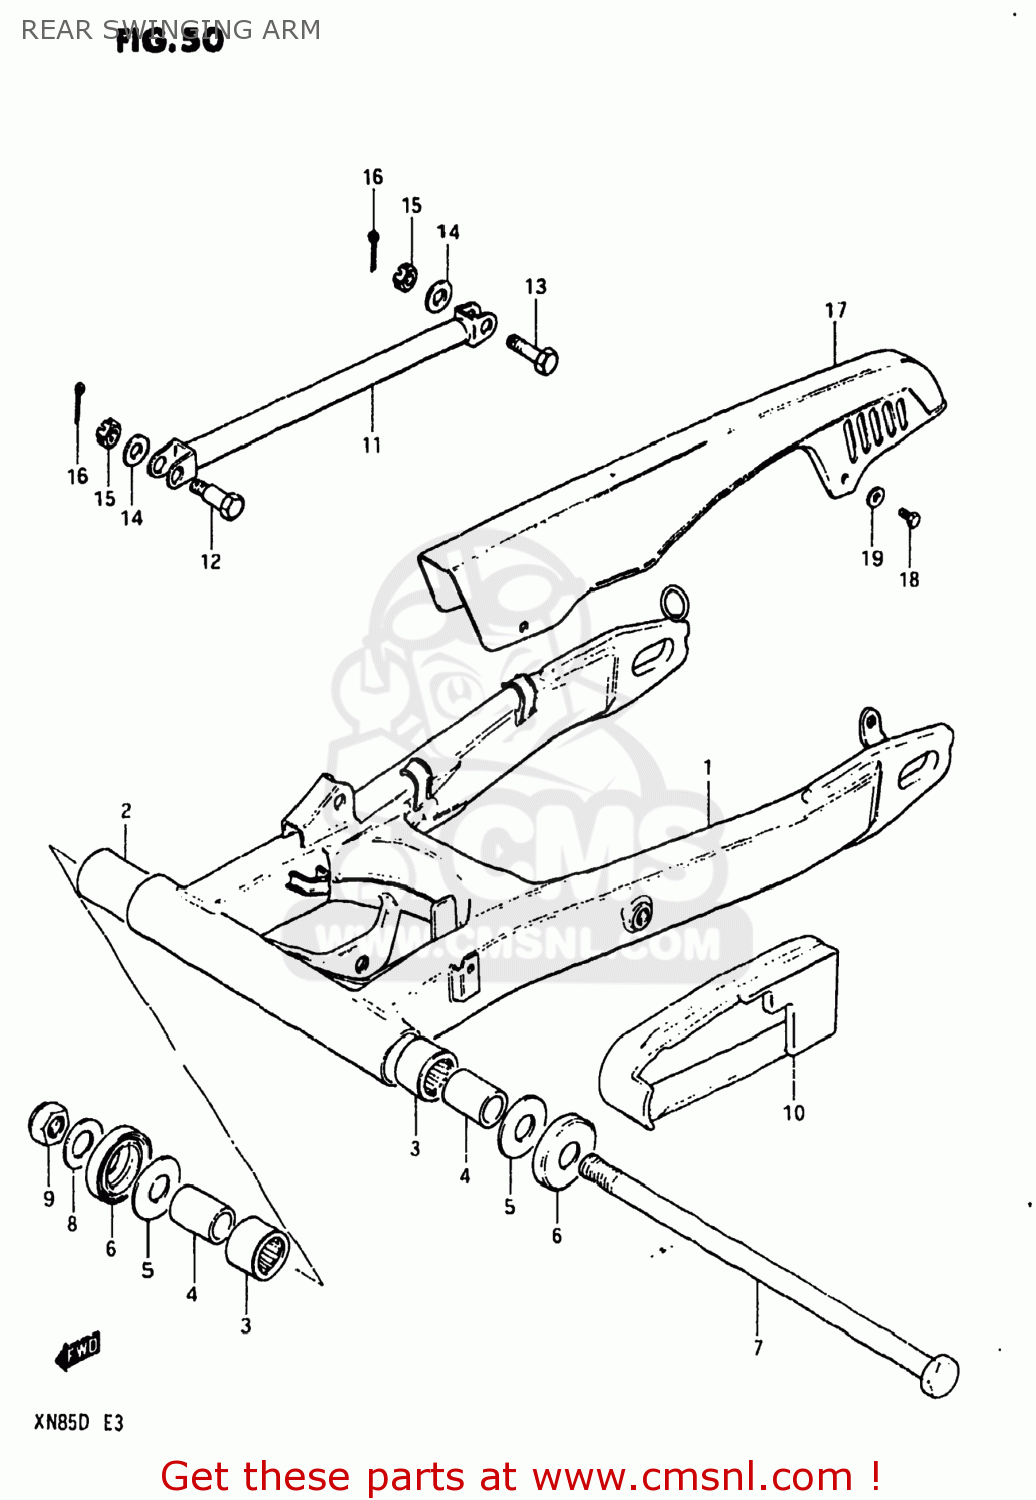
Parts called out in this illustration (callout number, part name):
1	ARM,REAR SWING
2	SPACER,SWING ARM,CENTER
3	BEARING(25X33X30)
4	SPACER,RR SWGARM PIVOT
5	WASHER
6	COVER,RR SWGARM DUST SEAL
7	SHAFT,REAR SWING ARM
8	WASHER
9	NUT
10	BUFFER,CHAIN TOUCH DEFLECTOR
11	LINK,REAR TORQUE
12	BOLT
13	BOLT(10X39)
14	WASHER
15	NUT
16	PIN 20X20
17	CASE,CHAIN
18	BOLT
19	WASHER
